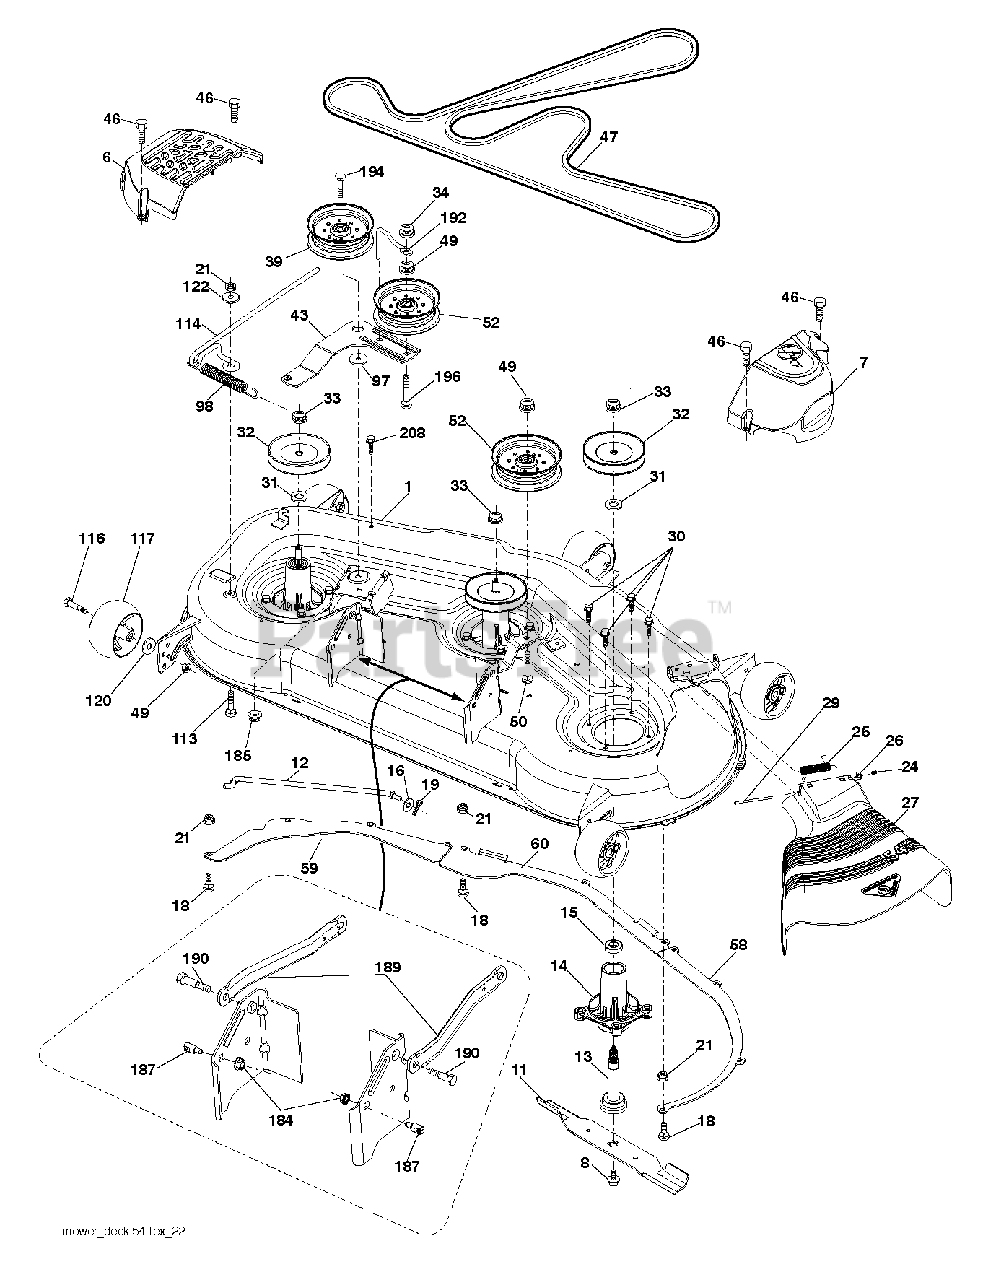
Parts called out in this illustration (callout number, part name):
1	DECK.WELDMENT.54'
6	COVER.MANDREL.LH.54"20
7	COVER.MANDREL.RH.54.20
8	BOLT.WASHER.ASM.7/16-2
11	BLADE, BAGGING 54"
12	ROD.ANTI.SWAY.48/54"TE
13	SHAFT ASM MANDREL
14	HOUSING MANDREL
16	WASHER
18	BOLT
19	PIN.COTTER.5/16.BOW TI
21	LOCKNUT
24	CAP-SLEEVE LT
25	SPRING, TORSION
27	DEFLECTOR
29	ROD.HINGE
30	SCREW, WASHER HEAD
31	WASHER.SPACER.MANDREL
32	PULLEY/MANDREL
33	NUT.FLANGE.LOCK.TOP
34	LOCKNUT
39	PULLEY.IDLER.4.50/HUB SPECIAL
46	SCREW.1/4-20X5/8
47	BELT.DRIVE.54."2006
49	NUT LOCK FLG 3/8-16 UNC
50	BOLT
52	PULLEY.IDLER.2006
58	BAFFLE.RIGHT.54"
59	BAFFLE.LEFT.54"
60	BAFFLE CENTER 54" MOWER
98	SPRING, DECK DRIVE
114	ROD TENSION RELIEF
116	BOLT.SHOULDER.3/8-16X3-5/8
117	WHEEL. GUAGE RALLY
122	BUSHING.RELIEF.TENSION
184	NUT LOCK HEX FLANGE 5/16-18
185	NUT.LOCK.FLANGE.7/16
187	STUD.FASTNER.W/ANTI-ROTATE
189	ARM.SUSPENSION.MOWER
190	BOLT.SHOULDER
192	KEEPER.BELT.IDLER.54"T
194	BOLT.HEX.WASHER.HEAD.7/16-24X
196	BOLT
208	SCREW 3/8-16X1/2
